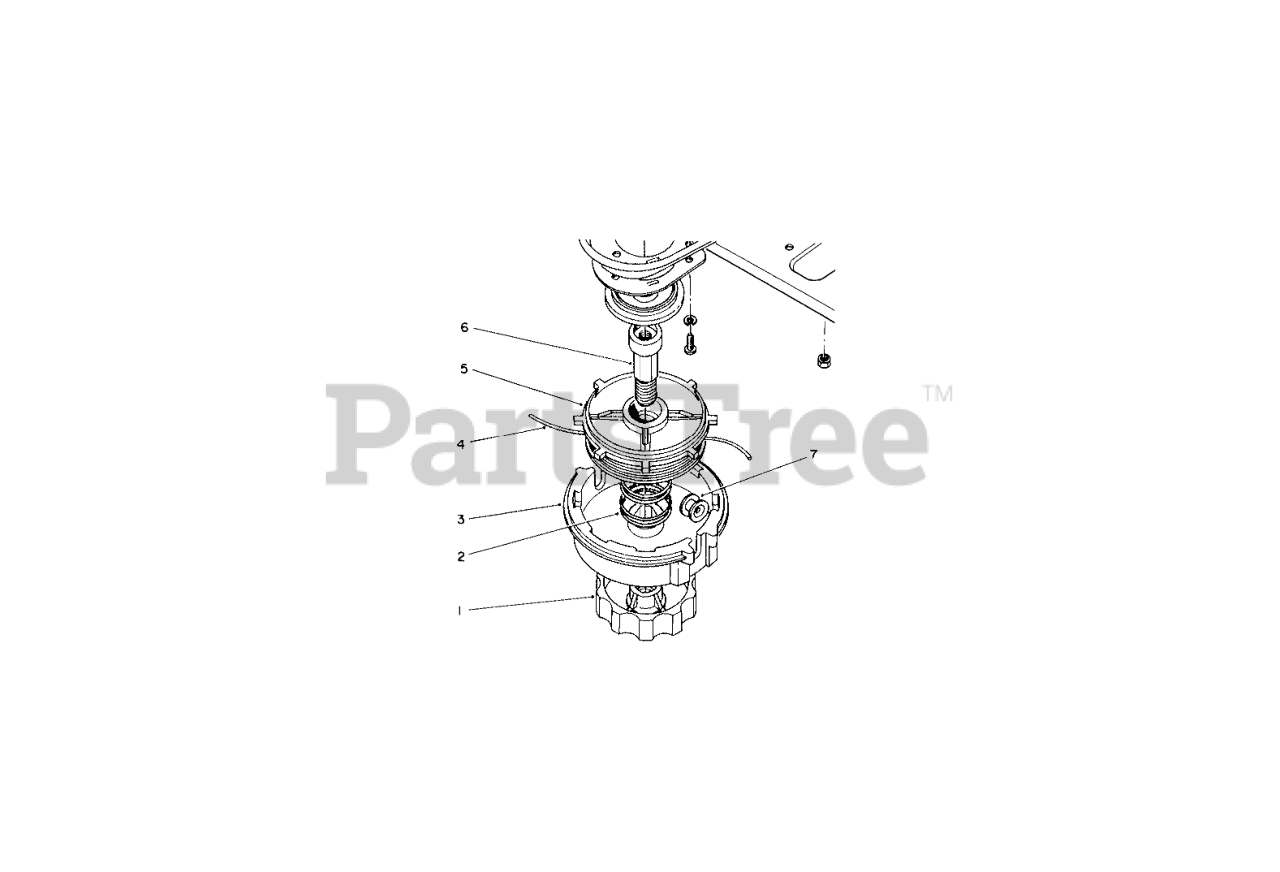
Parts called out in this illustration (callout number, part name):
1	LH KNOB(SERVICE ONLY)
2	SPRING (SERVICE)
3	Spool Housing
4	REPL LINE PKG
5	INNER SPOOL(SERV ONLY)
6	SHAFT (SERVICE ONLY)
7	EYELET(SERVICE)
